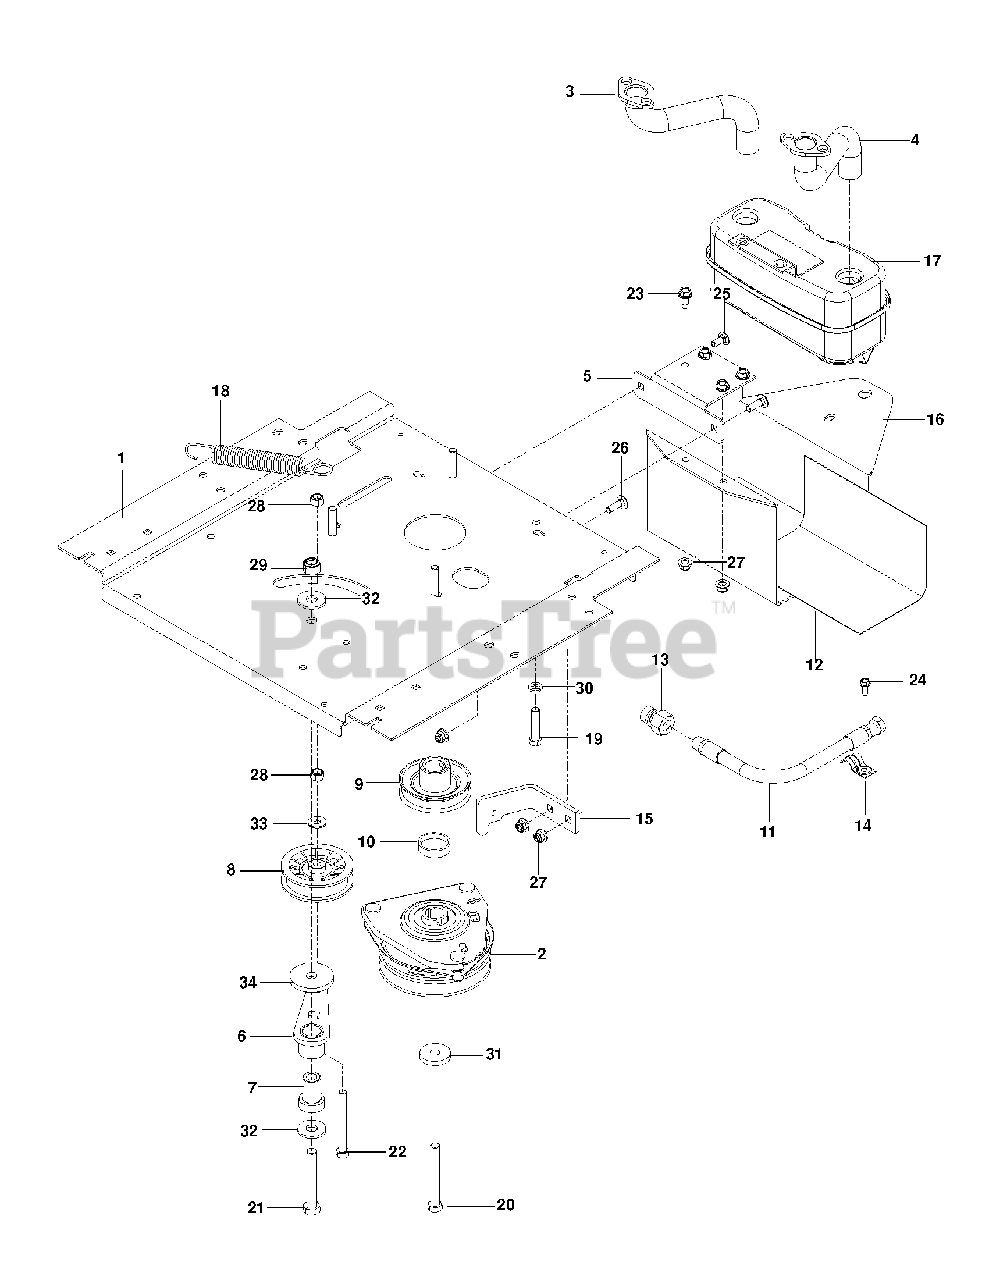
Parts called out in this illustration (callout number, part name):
1	PLATE, ENGINE BLK
2	CLUTCH.ELECTRIC.LT.48"*
3	EXHAUST PIPE ASM DUAL KAW RT
4	EXHAUST PIPE ASM DYAL KAW LT
5	BRACKET, MUFFLER, BLACK
6	IDLER ARM WELDMENT
7	IDLER SPINDLE
8	PULLEY, IDLER RAKE & ZTR
9	RP PULLEY, ENGINE
10	SPACER, HUB PULLEY
11	HOSE.ASSEMBLY.OIL.DRAIN
12	HEAT SHIELD
13	ADAPTER, OIL DRAIN
15	CLUTCH STOP OGR BLK
16	GUARD.MUFFLER.BLACK
17	MUFFLER OUTLET DUAL RZ
18	SPRING, DECK DRIVE
19	BOLT, HCS 3/8-16X1-3/4
20	CLUTCH BOLT7/16-20X2.5 GR524HR
21	HCS 1/2C X 3 1/4
22	HCS 3/8-16X3 1/2 GR5
23	BOLT 5/16-18 X 3/4
24	SCREW 1/4 X 5/8
25	RHSNB 5/16C X 1
26	BOLT 5/16C X 3/4" CARRIAGE
27	5/16-18 NYLOC FLANGE NUT
28	NUT 3/8-16 NYLOC
29	RP NUT 1/2-13 HEX NYLOC ZD
30	SLW 3/8 STD
31	CLUTCH, WASHER
32	WASH USS FLAT 1/2
33	WASHER 5/16 FLAT
34	HEAVY WASHER
